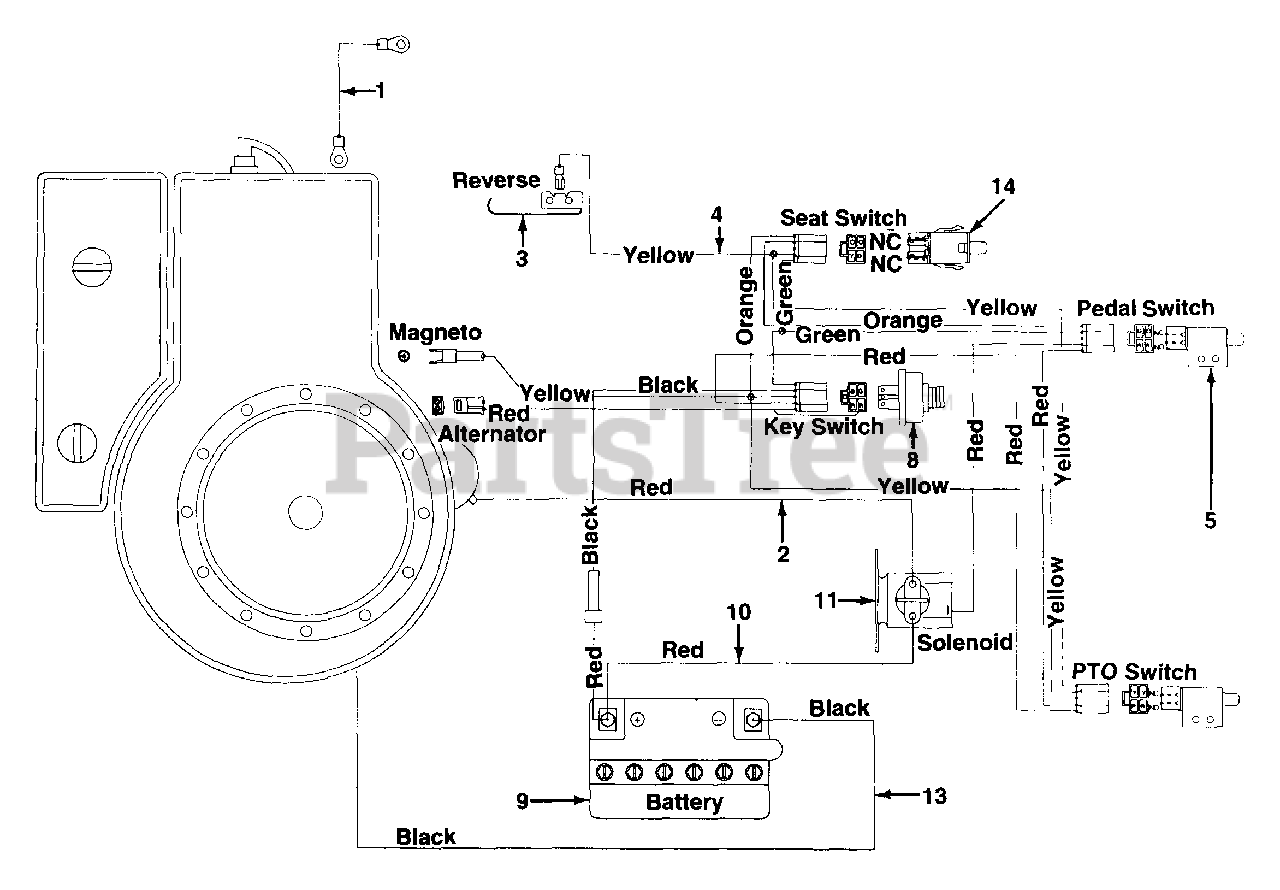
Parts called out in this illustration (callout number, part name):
1	Elec. Wire 8 Ga. x 9.0" Lg.
2	Elec. Wire
3	Spring Switch - Reverse
4	Wire Harness
5	Safety Switch
8	Ignition Switch
9	Battery 12V
10	Elec. Wire Red w/ Boot
11	Solenoid
13	Elec. Wire 8 Ga. x 9.0" Lg.
14	Seat Switch
